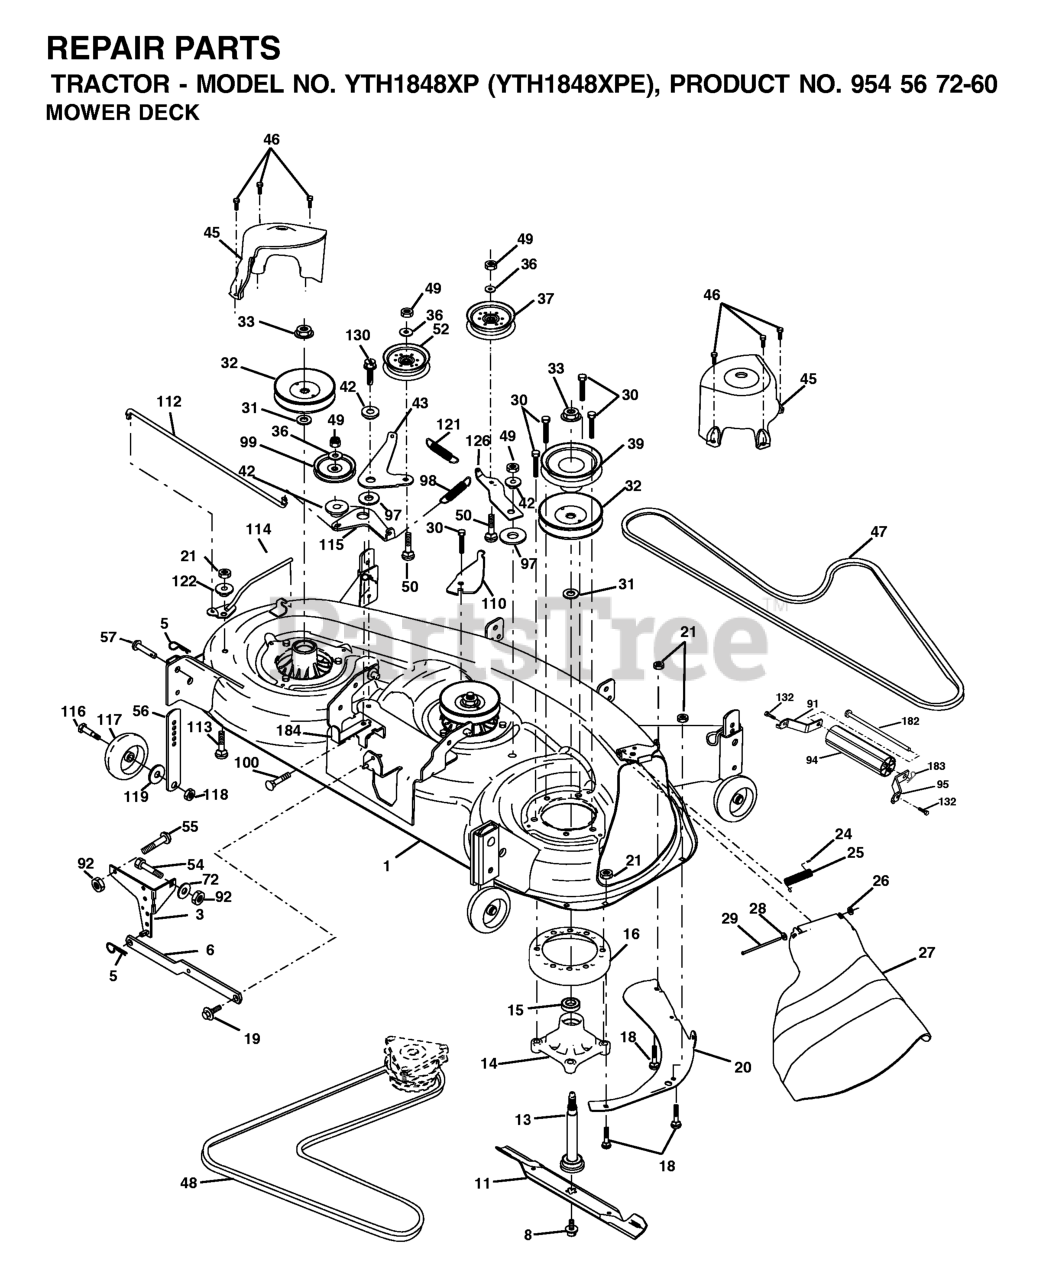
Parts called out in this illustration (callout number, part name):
1	DECK WELDMENT
3	BRKT ASM SWAY BAR
5	RETAINER-SPRNG RB
6	BAR SWAY DECK
8	BOLT 7/16 ASM BLADE
11	48" HI-LIFT BLADE
13	SHAFT ASM W/LOWER BEARING
14	HOUSING, MANDREL 48"
16	STRIPPER.MANDREL.ROUND.BLACK
17	BOLT
18	BOLT
19	BOLT SHD 5/16-18
20	BAFFLE, VORTEX MWR
21	LOCKNUT
24	CAP-SLEEVE LT
25	SPRING, TORSION
26	NUT PUSH M
27	DEFLECTOR SUBS TO 532 180655
28	Washer 11/32 x 5/8 x 16 Ga SD
29	ROD.HINGE
30	SCREW, WASHER HEAD
31	WASHER
32	PULLEY, MANDREL
33	NUT, FLG TOPLOCK 9/16"
36	WASHER
37	PULLEY.IDLER.FLAT
39	PULLEY.DRIVEN.DECK.48'
42	SPACER RETAINER
43	ARM, IDLER SECONDARY
45	COVER, MANDREL DECK
46	SCREW.1/4-20X5/8
47	V-BELT, MWR SECONDARY
48	V-BELT PRIMARY 48"
50	BOLT.3/8-16X1.50
52	PULLEY.IDLER.FLAT.46.PR.DR.
55	BOLT D
56	BAR.ADJUST.WHEEL.ANTI.SCALP.BL
57	RIVET.PIN.HEAD.YELLOW.
72	WASHER
91	BRKT.NOSEROLLER.LH.48"
92	NUT
94	NOSE ROLLER 48"
95	BRKT.NOSEROLLER.RH.48"
97	HARDENED WASHER
98	SPRING PRIMARY DRIVE
99	PULLEY,IDLER"V"
107	BAFFLE.VAC.EDGE.MOWER.48"
109	NUT.CROWNLOCK.1/4
110	ARM, SPRING SECONDARY
112	LEVER, TENSION RELIEF LINK
114	LEVER ASM, TENSION RELIEF
115	ARM, SPRING TENSION RELIEF
116	BOLT, SHOULDER
117	WHEEL GAGE DONUT
118	LOCKNUT
119	WASHER.5/16.FLAT.STE.STD.
121	SPRING.DRIVE.SECONDARY.48".DEC
122	BUSHING, PIVOT TENSION RELIEF
126	ARM, IDLER PRIMARY DECK
130	SCREW 3/8-16X1
132	SCREW 3/8-16X3/4
182	ROD.ROLLER.NOSE.NARROW.48"
183	SPRING RETAINER
184	KEEPER BELT IDLER PLATED
